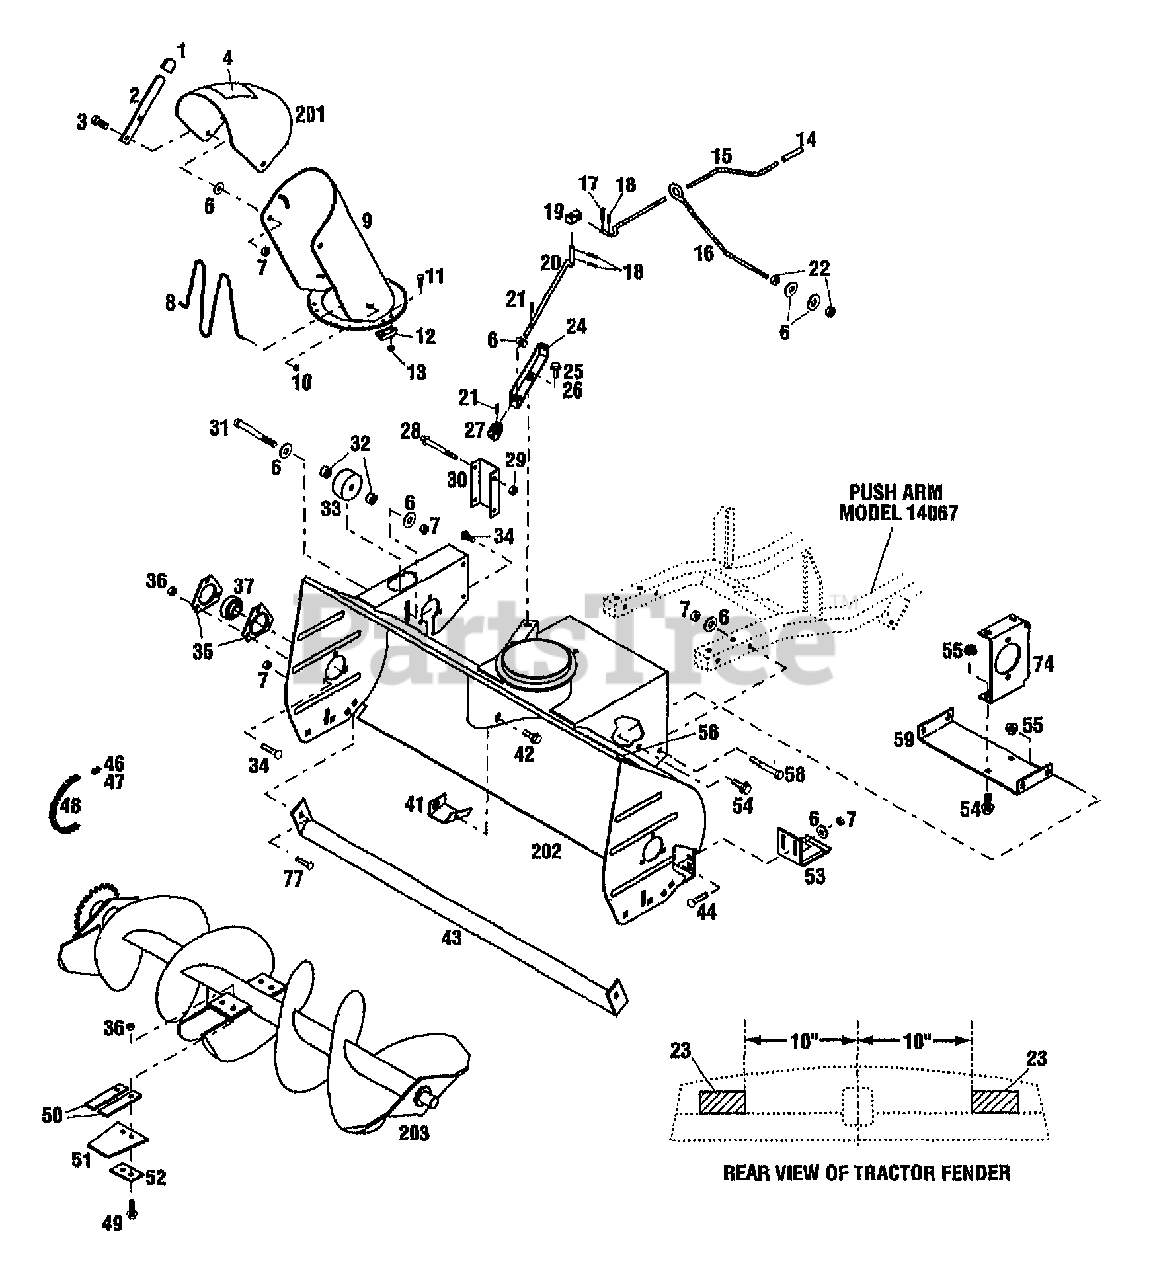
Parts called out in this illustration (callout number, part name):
1	GRIP-VACUCUT
2	LEVER-ADJUSTING
3	SCR-HH 3/8-16X.75 G5 ZP
4	DECAL-WARNING
6	WASHER-FLAT 3/8 SAE
7	NUT-LOCK 3/8-16
8	GUARD-CHUTE
9	ASSM-DISCHARGE CHUTE
10	NUT-PUSH 3/16
11	SCR-SEMS MACH
12	CLIP-HOLD DOWN
13	NUT-H/LK M10-24 NYLOCK
14	GRIP-PLASTIC
16	SCR-EYE
17	PIN-COTTER .125 X .75 ZP
18	PIN-ROLL 1/8 X 3/4
19	BLOCK-SWIVEL NYLON
20	SHAFT-PINION
21	PIN-DRIVE .09X.75
22	NUT-HEX 3/8-16 ZP
23	REFLECTOR
24	SUPPORT-SHAFT
25	SCR-HFLK 5/16-18X.75 ZP
26	NUT-HFLK 5/16-18 ZP
27	GEAR-WORM LH
28	SCR-HH 1/4-20X3.0 G5 ZP
29	NUT-HT LK 1/4-20
30	COVER-END
31	SCR-HH 3/8-16X3.0 G5 ZP
32	SPACER-.68X.39X.46
33	BLOCK-TENSION
34	SCR-CARR 5/16-18X.75 G2 ZP
35	BEARING-FLANGE
36	NUT-TOP/LK 5/16-18 ZP
37	BEARING & COLLAR
41	ASSM-DEFLECTOR
42	SCR-HH 3/8-16X.50
43	BLADE-SCRAPER
44	SCR-CARR 3/8-16X1.00
46	LINK-CONNECTOR
47	LINK-OFFSET
48	CHAIN-DRIVE
49	SCR-HFLK 5/16-18X1.25 ZP
50	SLINGER EXTENSION
53	SHOE-SKID
55	NUT-HFLK 3/8-16 ZP
56	DECAL-WARNING
58	SCR-HH 3/8-16X2.25 G5 ZP
59	SUPT-HOUSING
74	SUPPORT-GEAR BOX
77	BOLT-3/8-16 X 3/4
201	ASSM-DISCHARGE CAP
202	HSG W/DECALS
203	ASSY-ROTOR 42"
